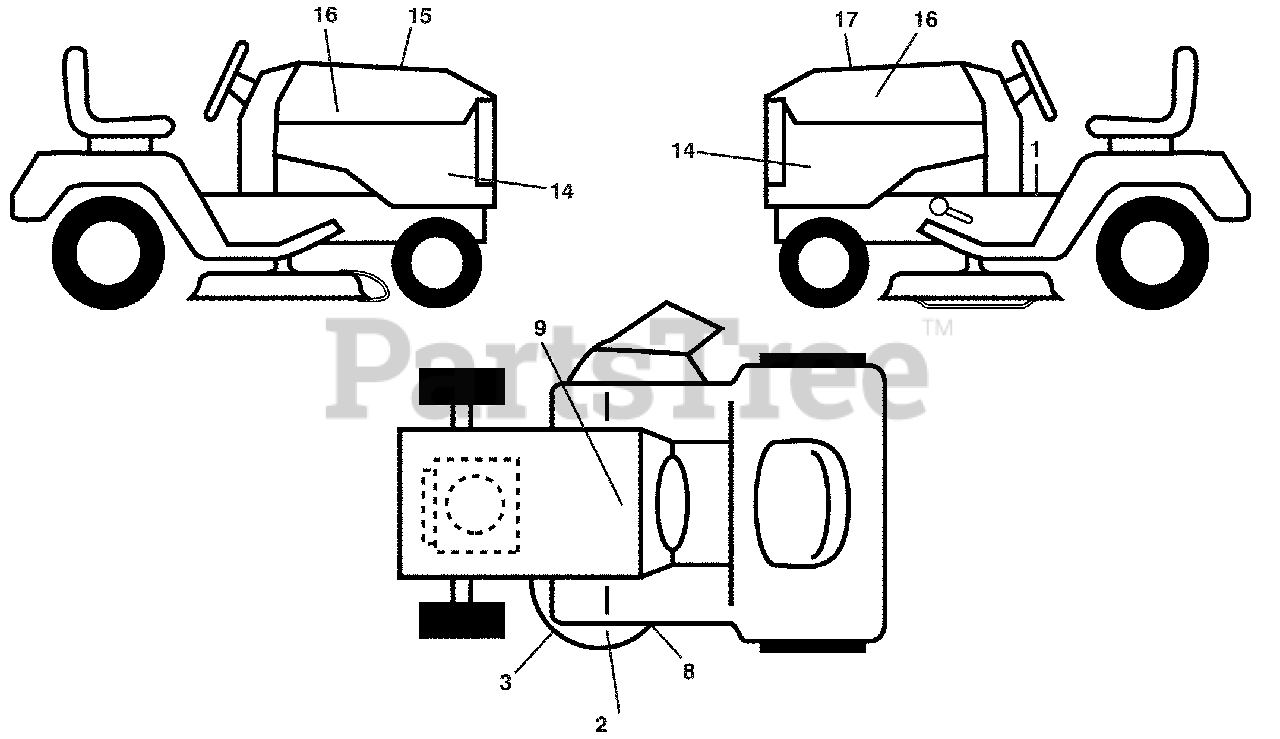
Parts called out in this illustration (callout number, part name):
1	Decal, Operator’s
2	Decal, Deck Airinduct
3	Decal, Warning
8	Decal, Mower Sch.
9	Decal, Battery Dnge/Poi
14	Decal, Panel Side
15	Decal, Cust. Resp.
16	Decal, Emblem Hood
17	Decal, Replacement
